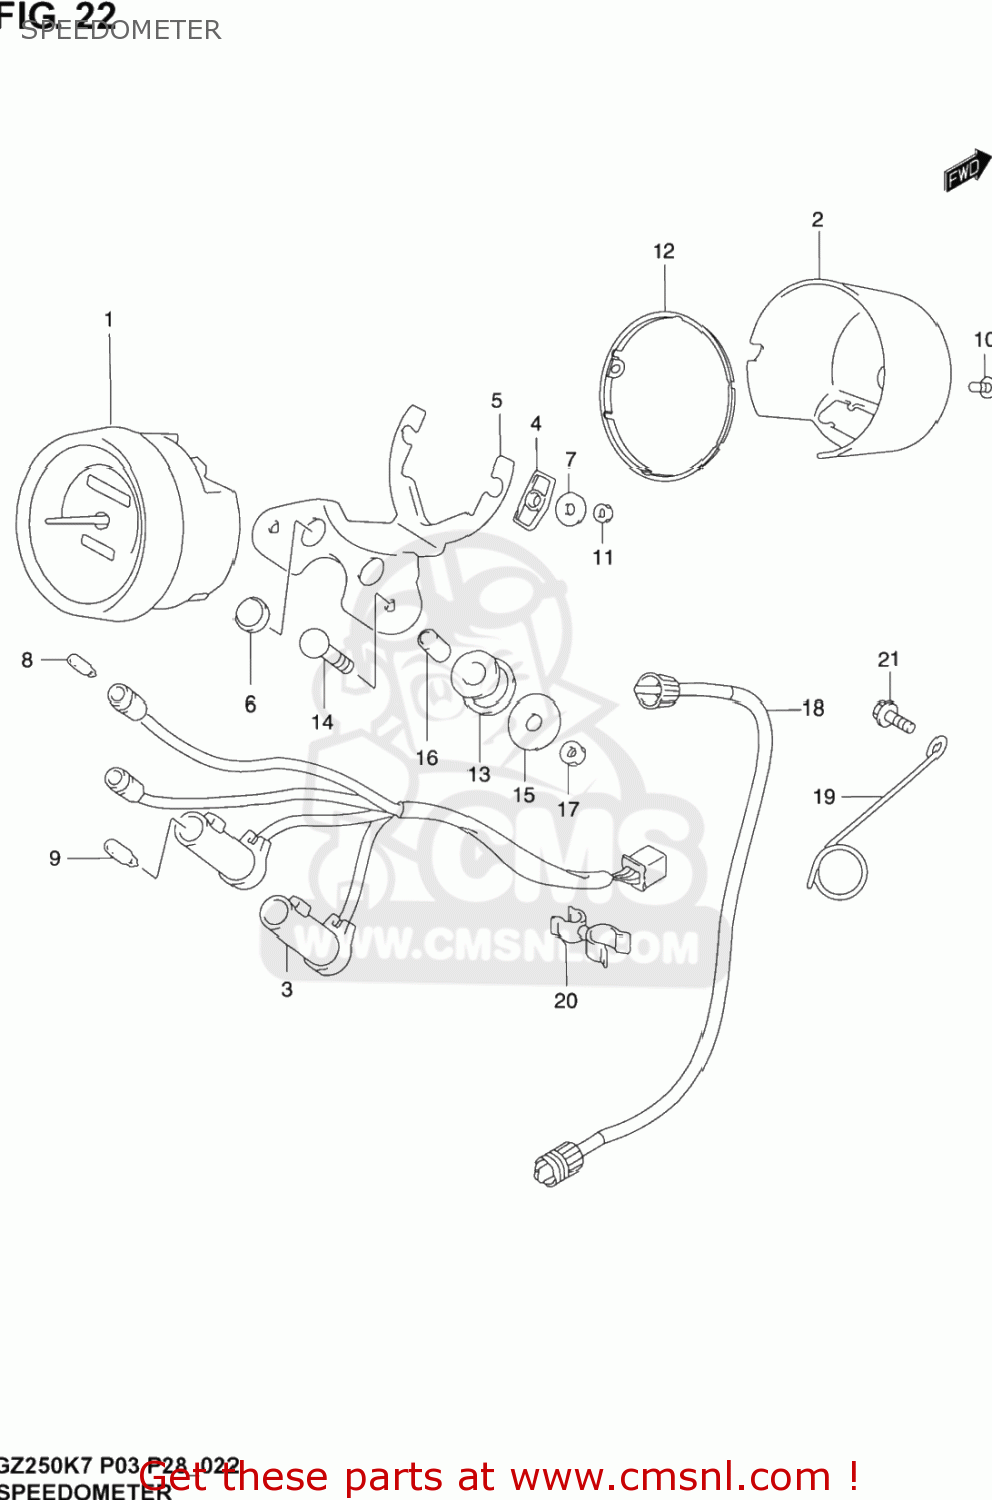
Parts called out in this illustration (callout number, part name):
1	SPEEDOMETER
2	COVER, UNDER
3	SOCKET, ASSY
4	CUSHION,DAMPER
5	BRACKET, METER
6	LENS, GREEN
7	WASHER
8	BULB(12V3.4W,T10)
9	BULB(12V1.7W,T6.5)
10	SCREW,METER
11	NUT
12	PACKING (NAS)
13	CUSHION,METER BRACKET
14	BOLT(6X30)
15	WASHER(6.5X28X1.6)
16	SPACER(6.5X10X16.5)
17	NUT 6MM
18	CABLE ASSY,SPEEDOMETER
19	GUIDE,SPEEDOMETER CABLE
20	CLAMP
21	BOLT
